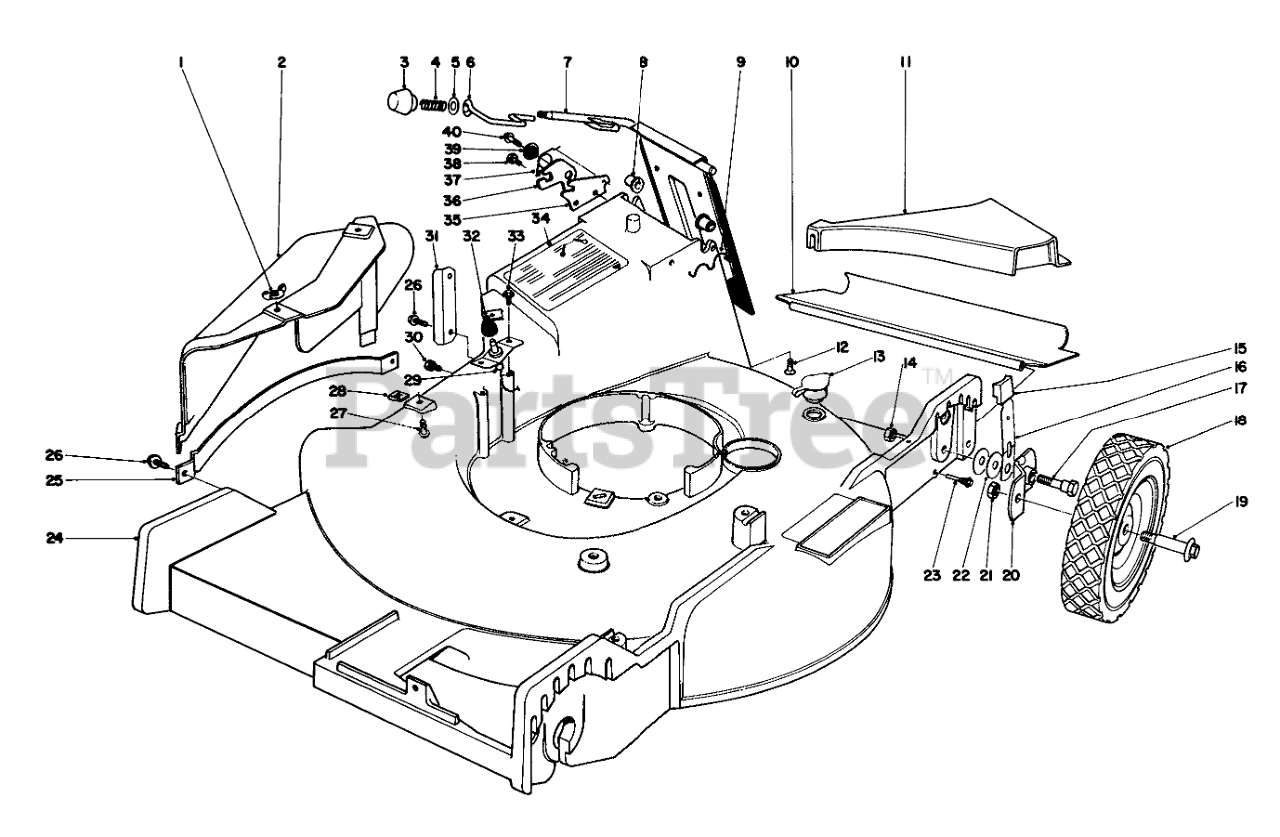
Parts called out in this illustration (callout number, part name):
1	NUT-WING SPECL
2	DEFLECTOR
4	COMPRESSION SPRING
5	WASHER
6	DOOR LATCH
7	Door Handle
8	BUSHING-NYLON
9	Door Retainer
10	REAR SAFETY SHIELD
11	REAR INSERT
12	SCREW-HH
13	WASHOUT PLUG
14	Nut
15	Knob
16	SPRING ARM ASM
17	PIVOT SCREW
18	Wheel Assembly
20	PIVOT ARM ASM A
21	Nut
22	WASHER-PIVOT
23	SAFTEY SHIELD SCREW
24	Housing
25	Bar Safety
26	SCREW
29	Deflector Switch (Incl. Ref. #32)
30	SCREW THD 1/4 20 5/8
31	Clip Retaining
32	Boot Switch
34	Decal-Caution
35	DOOR LATCH PLATE
36	Latch Safety
37	TORSION SPRING
38	SCREW-HWH
39	Latch Spacer
40	Screw
